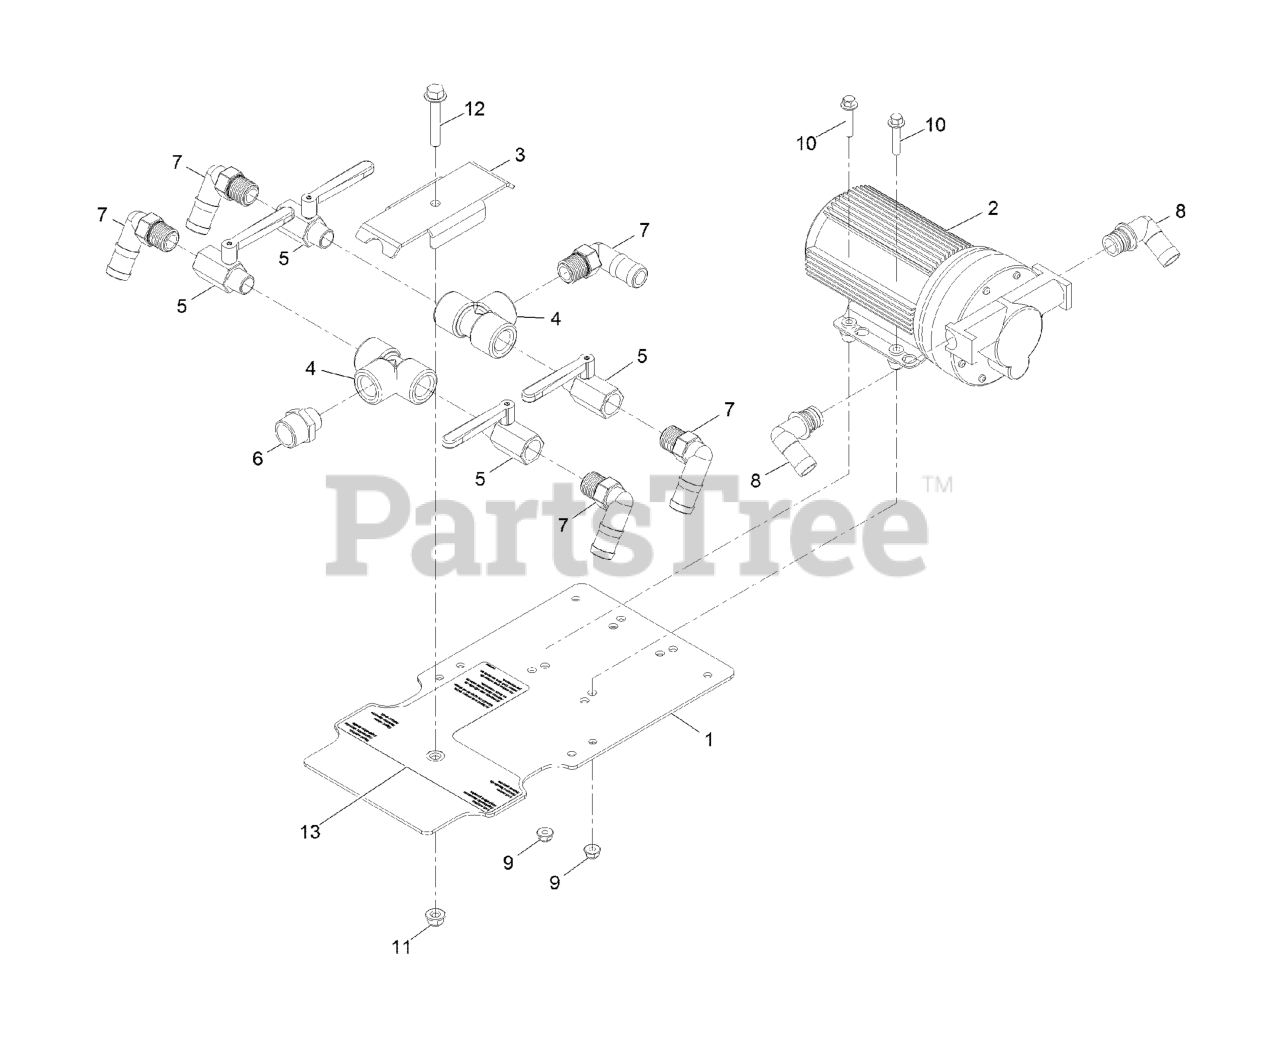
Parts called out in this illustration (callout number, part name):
1	MOUNT-PLATE, LIQUID VALVE
2	PUMP-5.0 GPM
3	PLATE-CLAMP, LIQUID VALVE
5	VALVE-CHROME, 1/2
6	FITTING-NIPPLE
7	ELBOW-90
8	FITTING-ELBOW, 3/4QD X 3/
9	Nut-Hex Flange
10	SCREW-HHF
11	Nut-Hex Flange
12	SCREW-HHF
13	DECAL-VALVE, TANK
